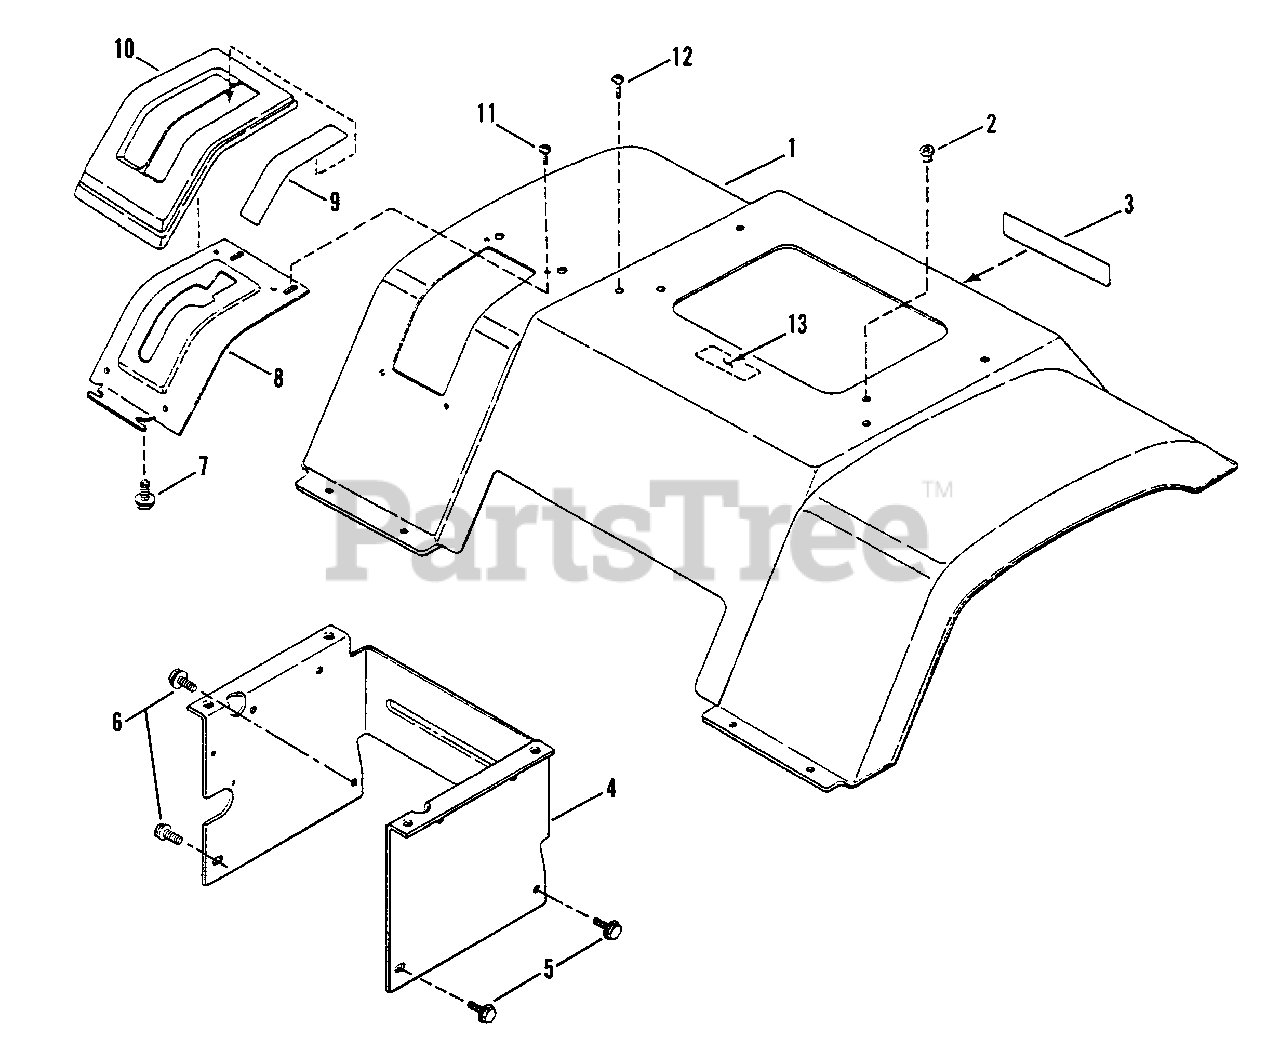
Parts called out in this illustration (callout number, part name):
1	PAN, Seat (Fender)
2	RIV-NUT, 5/16-18
3	DECAL - SNAPPER, 7.28 Molded Logo
4	SUPPORT, Fender
5	SCREW, 5/16-18 x 5/8" Hex Washer Head, Self-Tapping
6	SCREW, 5/16-18 x 1 1/4" Hex Washer Head, Self-Tapping
7	SCREW, #10-16 x 1/2" Hex Washer Head, Self-Tapping
8	DETENT, Gear Shift
9	DECAL, Shift Cover, 5-Speed
10	COVER, Shift
11	SCREW, 1/4-20 x 5/8" Truss Head (Torx)
12	SCREW, 5/16-18 x 5/8" Truss Head (Torx)
13	DECAL - CAUTION, Battery Location
